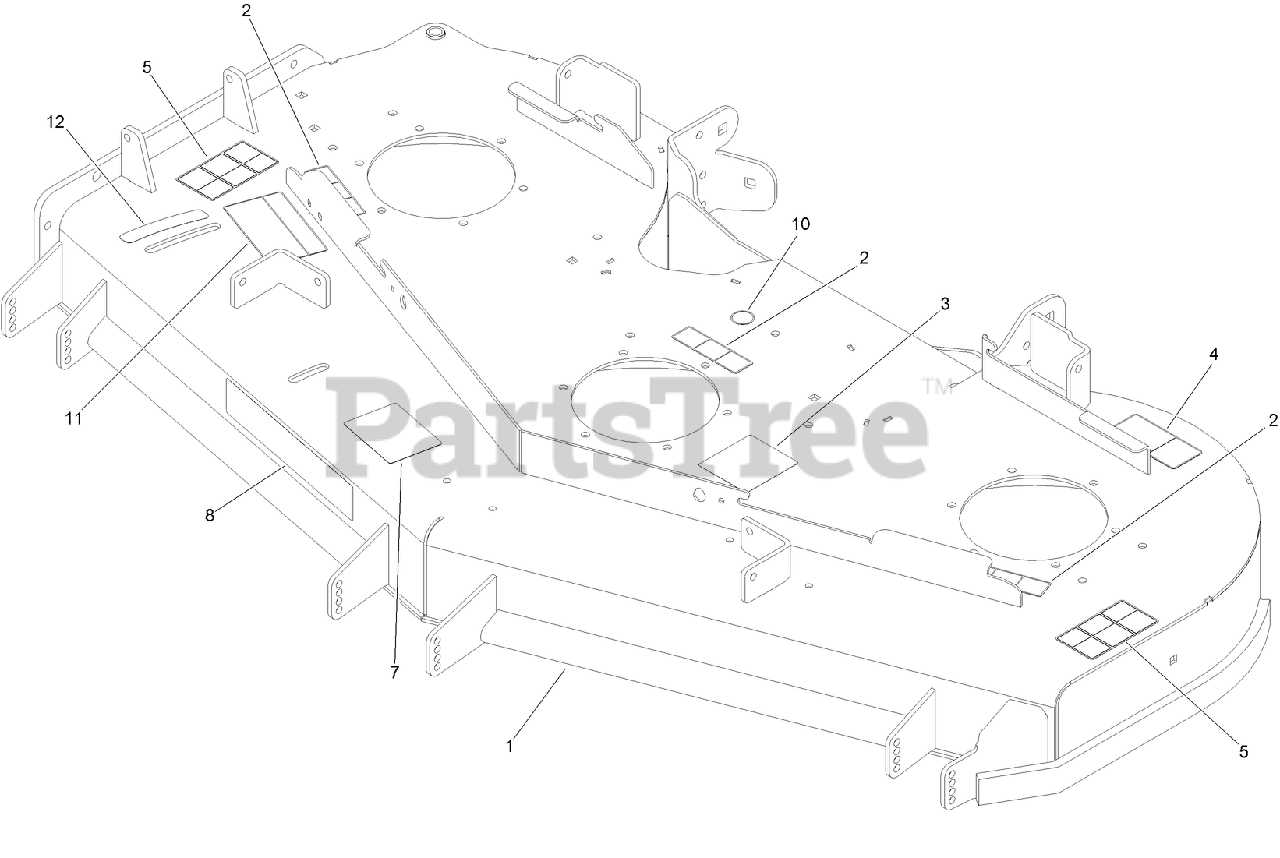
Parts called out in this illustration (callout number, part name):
1	DECK DECAL ASM
2	DECAL-COVER, MISSING
3	DECAL-ROUTING, DECK BELT
4	DECAL-TORQUE, BLADE BOLT
5	DECAL-DANGER
7	DECAL-SCALP, ANTI
10	DECAL-GREASE
11	DECAL-ADJUSTMENT, BAFFLE
12	DECAL-SETTING, BAFFLE
